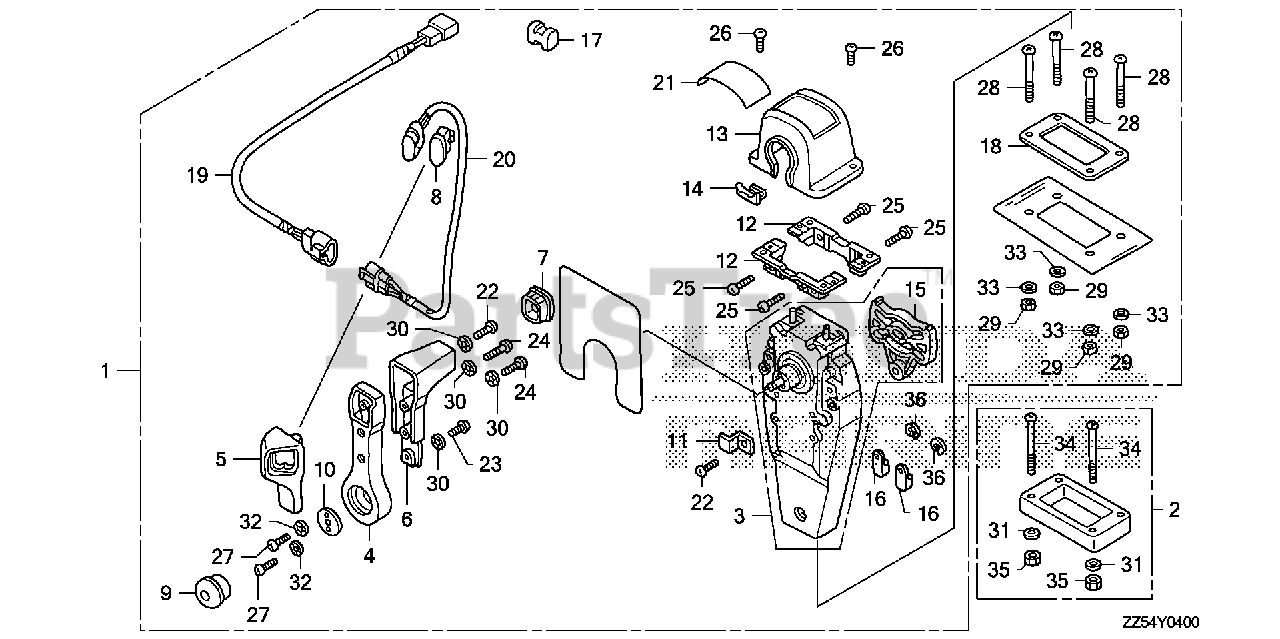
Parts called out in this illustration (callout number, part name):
1	BOX KIT, REMOTE CONTROL (TOP MOUNT SINGLE)(R)
2	SPACER KIT, REMOTE CONTROL BOX (TOP MOUNT SINGLE)
3	HOUSING ASSY., L. (INNER) (TOP MOUNT)
4	HANDLE, REMOTE CONTROL
5	COVER, L. GRIP
6	GRIP, REMOTE CONTROL HANDLE
7	CAP, GRIP
8	CAP, SWITCH
9	BUTTON, THROTTLE
10	PLATE, HANDLE
11	PLATE, CABLE CLAMP
12	BRACKET, REMOTE CONTROL HOUSING
13	HOUSING, REMOTE CONTROL BOX
14	HOUSING, LEAD
15	PLATE, DWELL
16	TERMINAL, CABLE
17	SPACER, CABLE CLAMP
18	GASKET, SINGLE
19	SUB-HARNESS ASSY., POWER TRIM-TILT (A)
20	SWITCH ASSY., POWER TRIM-TILT (A)
21	MARK, REMOTE CONTROL (SINGLE)
22	SCREW, PAN (5X16)
23	SCREW, PAN (5X10)
24	SCREW, PAN (5X20)
25	SCREW, PAN (5X18)
26	SCREW, PAN (4X10)
27	SCREW, PAN (6X18)
28	SCREW, PAN (5X40)
29	NUT, HEX. (5MM)
30	WASHER, LOCK (5MM)
31	WASHER, PLAIN (5MM)
32	WASHER, LOCK (6MM)
33	WASHER, PLAIN (5MM)
34	SCREW, PAN (5X65)
35	NUT, HEX. (5MM)
36	E-RING (6MM)
